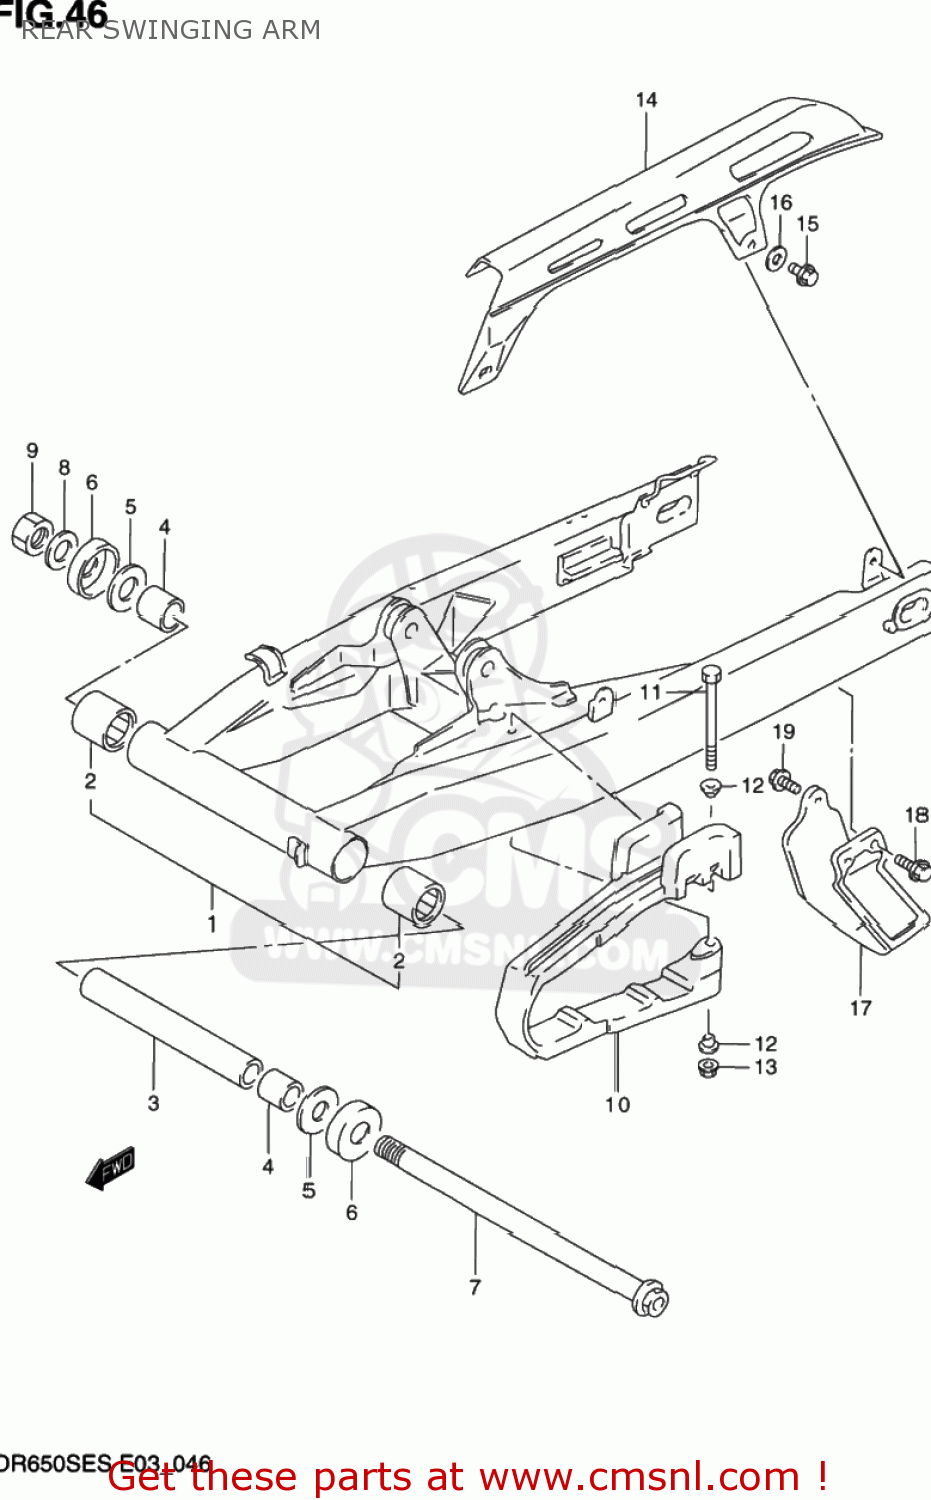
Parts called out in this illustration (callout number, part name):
1	SWING ARM ASSEMBLY,REAR
2	BEARING(22X29X20)
3	SPACER,RR SWGARM PIVOT CTR
4	SPACER,RR SWGARM PIVOT
5	WASHER
6	SEAL,RR SWGARM PIVOT DUST
7	SHAFT,REAR SWING ARM
8	WASHER
9	NUT 16MM
10	BUFFER,CHAIN TOUCH DEFENSE
11	BOLT,TOUCH DEFENSE FTG
12	WASHER
13	NUT
14	CASE,CHAIN
15	BOLT
16	WASHER
17	GUIDE,CHAIN
18	BOLT
19	BOLT
